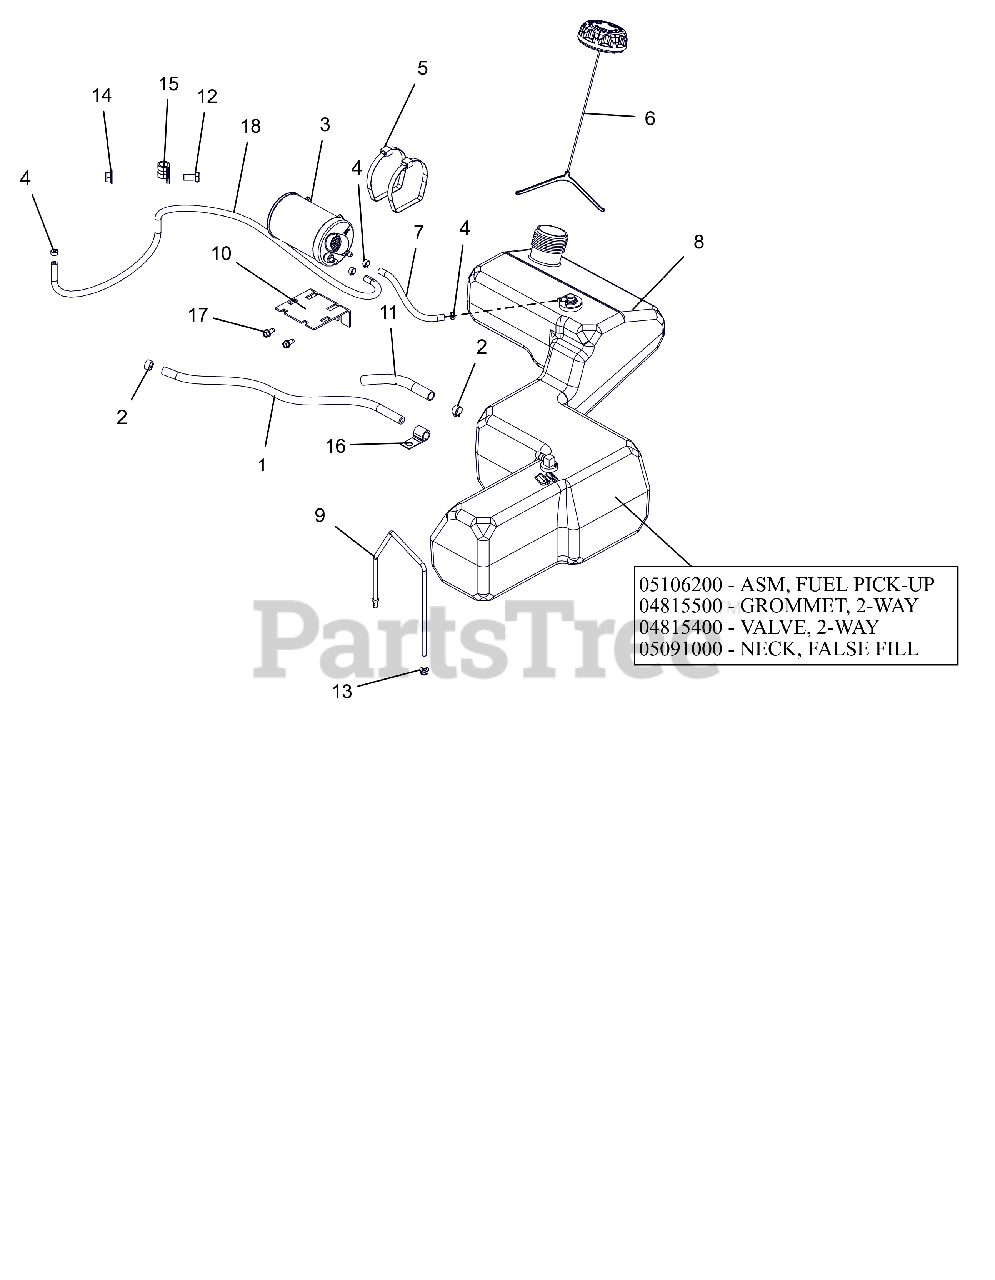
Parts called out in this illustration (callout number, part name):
1	HOSE, .25 LOW-PERM BULK GAS
2	CLAMP, FUEL LINE
3	CARBON CANISTER, 300CC
4	CLAMP-HOSE, SPRING .188
5	P-PLASTIC TIE STRAP LARGE
6	CAP, FUEL VENT-IN 2.25" RATCH.
7	HOSE, .188 30R7 BULK
8	ASSEMBLY, FUEL TANK IKON(2017)
8	ASM, IKON FUEL PICK-UP
8	GROMMET, 2-WAY
8	VALVE, 2-WAY
8	NECK, FALSE FILL-2017 IKON
9	BRKT, FUEL TANK HOLD DOWN
10	BRKT, MOUNT -CARB CANISTER
11	WRAP, ANTIABRASION .5X.064WALL
12	@BLT-HEX .38-16X.75 GR5 YWZC
13	@NUT-LK-NYL-FLG .25-20 YWZC
14	@NUT-LK-NYL-FLG .38-16 YWZC
15	CLAMP, CUSHIONED STEEL
16	J-CLAMP
17	SCR-TAP .25-20X.50 HWH TR YWZ
18	HOSE, .188 30R7 BULK
